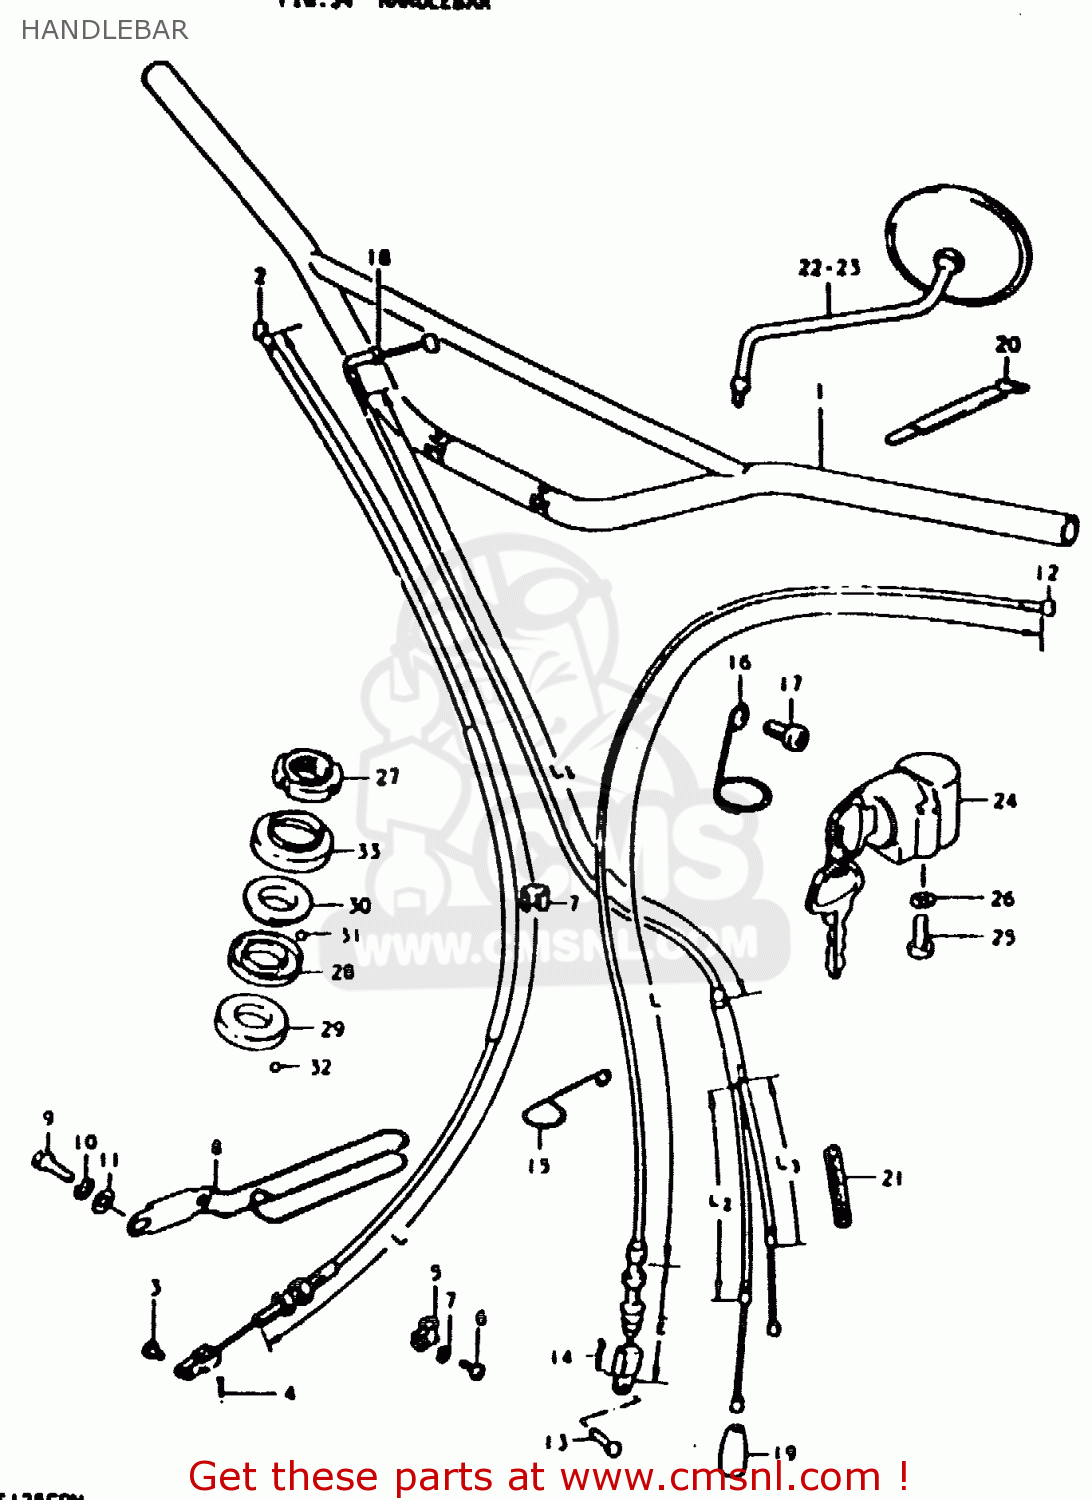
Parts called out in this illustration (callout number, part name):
1	HANDLEBAR
2	CABLE,FR BRAKE
3	PIN(L:13.5)
4	PIN
5	GUIDE,CABLE
6	SCREW
7	LOCK WASHER
8	GUIDE,CABLE
9	BOLT 8X12
10	LOCK WASHER
11	WASHER
12	CABLE ASSEMBLY,CLUTCH
13	PIN(L:15)
14	PIN
15	CLAMP
16	CLIP
17	SCREW
18	CABLE ASSEMBLY,THROTTLE
19	SEAL,DUST(7X18X30)
20	CLAMP
21	PROTECTOR,CABLE
22	MIRROR ASSEMBLY,RIGHT
23	MIRROR ASSEMBLY,LEFT
24	LOCK ASSEMBLY,STEERING
25	SCREW
26	LOCK WASHER
27	NUT,STEERING STEM(25X44X10)
28	RACE,STEERING INNER UPR
29	LACE,STEERING INNER LWR
30	RACE,STEERING OUTER UPR
31	BALL
32	BALL
33	DUST SEAL,STEERING UPR
